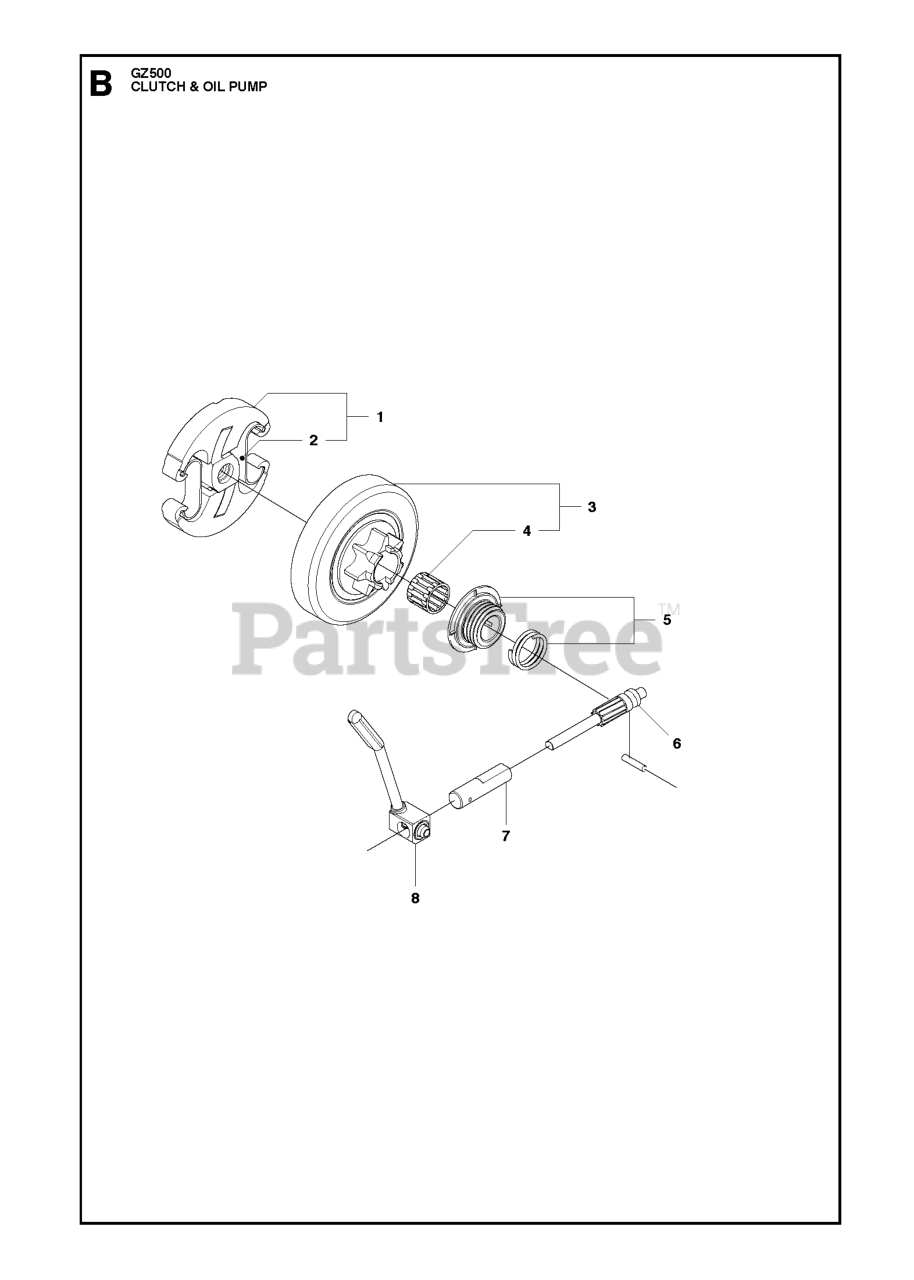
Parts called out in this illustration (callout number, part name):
1	CLUTCH ASSY
3	CLUTCH DRUM
4	NEEDLE BEARING
5	GEAR WHEEL OIL PUMP
6	PISTON PUMP
7	PUMP CYLINDER
8	OIL HOSE
